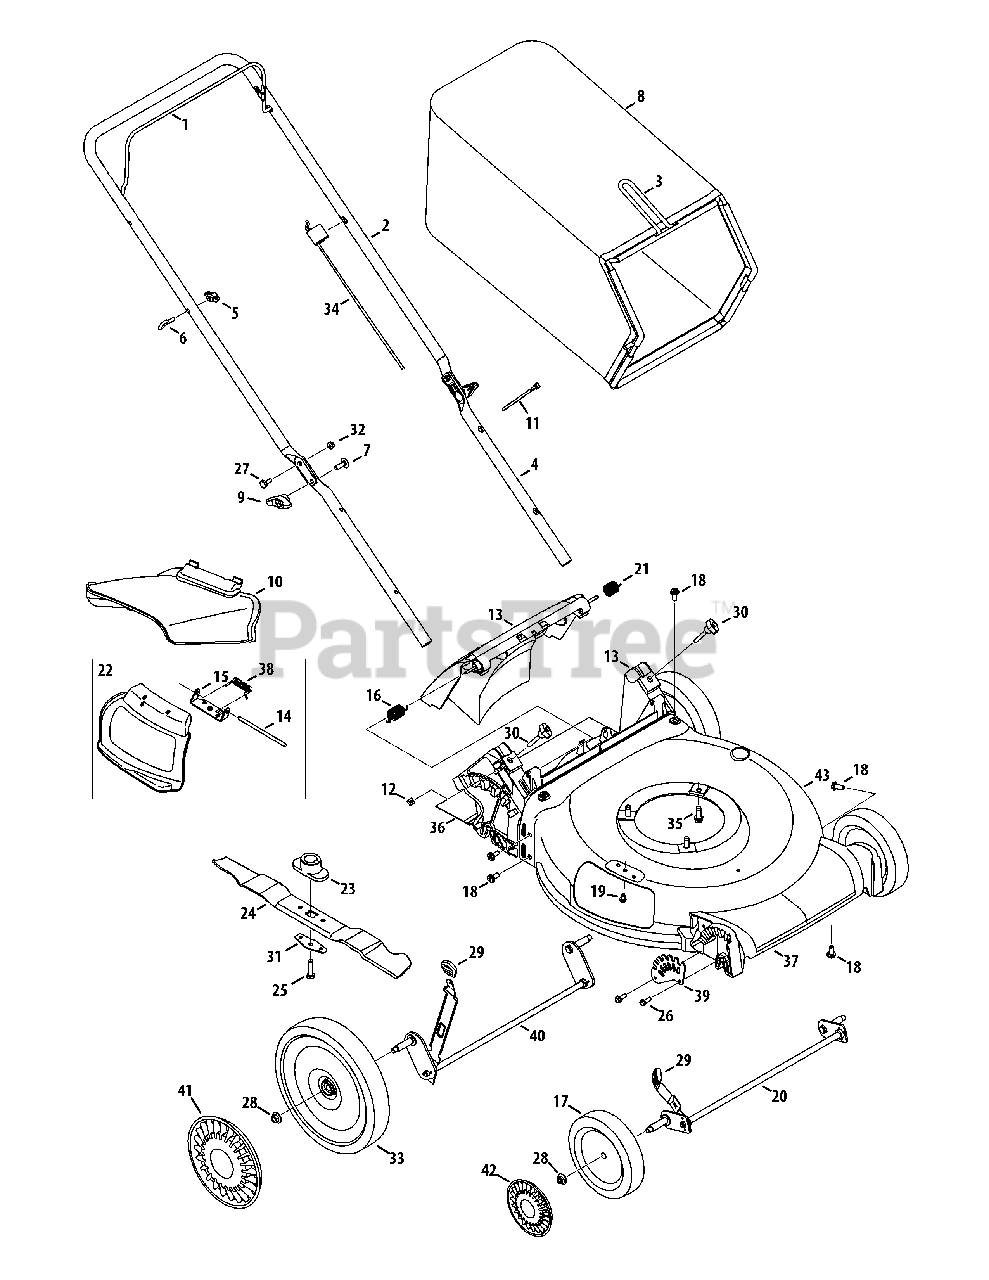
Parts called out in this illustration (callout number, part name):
1	Blade Control, Standard
2	Upper Handle, Adjustable
3	Grass Catcher Frame
4	Lower Handle
5	Wing Nut
6	Rope Guide
7	Carriage Screw ,5/16-18
8	Grass Bag, Black
9	Wing Knob, Black
10	Side Chute
11	Cable Tie
12	Nut, Sq., 1/4-20
13	Rear Discharge Door Assembly
14	Hinge Pin
15	Chute Deflector Bracket
16	Torsion Spring - RH
17	Front Wheel Black
18	Screw, 5/16-14 x .750
19	Screw, 1/4-20 x .500
20	Front Axle Assembly
21	Torsion Spring - LH
22	Hinged Mulch Plug Assembly
23	Blade Adapter, #6 x 1.19 w/ Star
24	Mulching Blade
25	Screw , 3/8-24 x 1.50
26	Screw, 1/4-15 x .750
27	Sldr. Screw, .375 x .126 x 1/4-20
28	Flange Lock Nut, 3/8-16
29	Adjustment Lever Knob
30	Wing Nut
31	Blade Bell Support
32	Nut, Flange Lock, 1/4-20
33	Rear Wheel Black
34	Control Cable, 37.58"
35	TT Sems Screw, 3/8-16 x 1.0
36	Trail shield
37	Front Cover
38	Torsion Spring
39	Front Height Adjuster Plate
40	Rear Axle Assembly
41	Hubcap, 11"
42	Hubcap, 7" w/o snaps
43	Deck , 21" - Black
